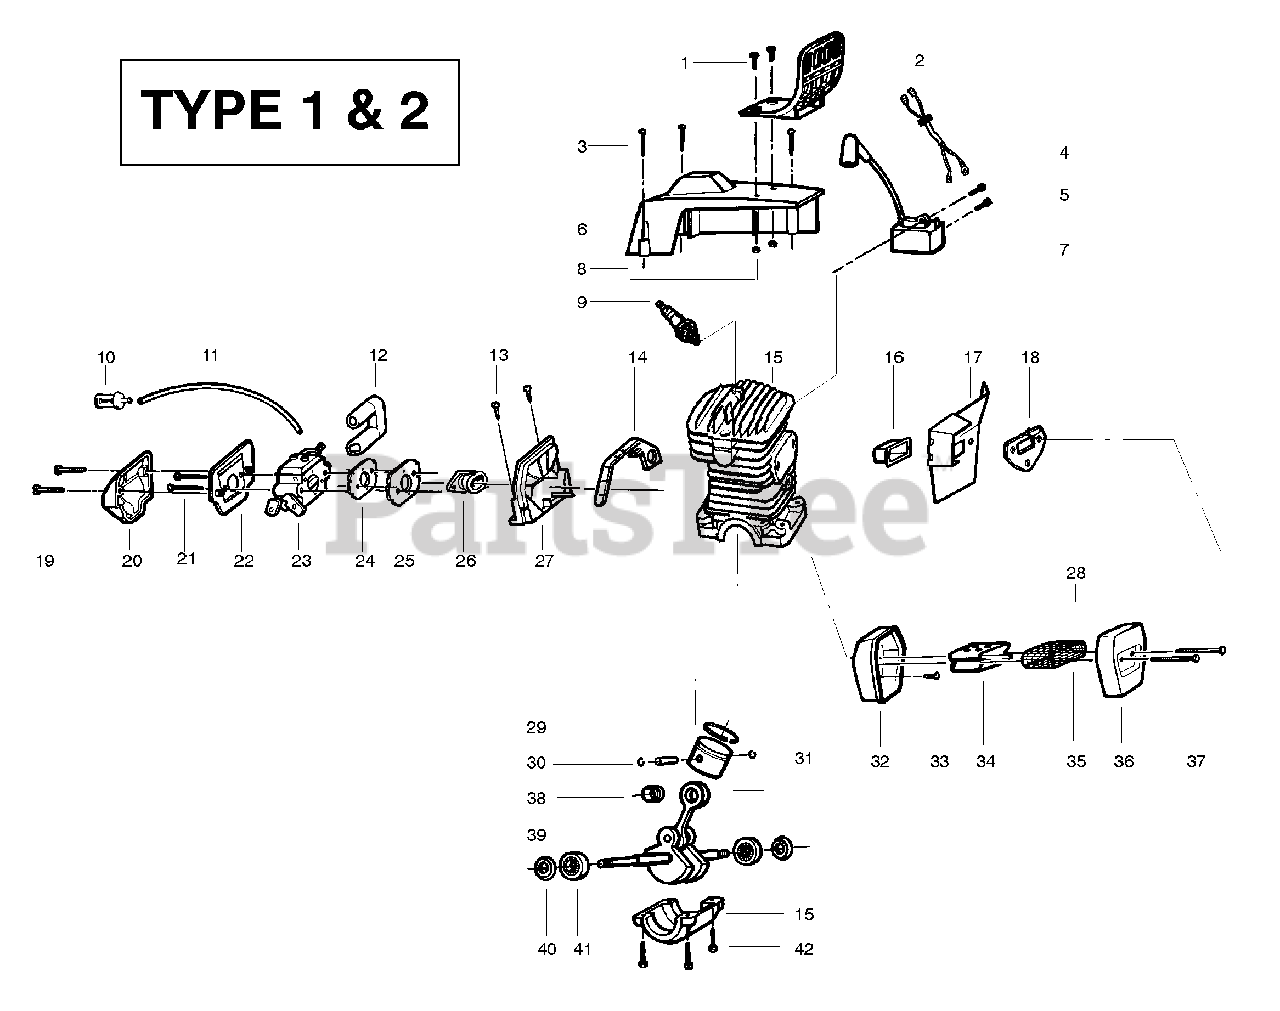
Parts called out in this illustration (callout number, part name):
1	Screw
2	Handguard
4	Switch Wire Ass'y.
6	Cylinder Shield Kit
7	Ignition Module
8	Nut
9	Spark Plug
10	Fuel Pick-up Assy.
11	Kit - Line Carb / Purge
12	Carb. Grommet
14	Super Clean Seal
15	C'case&Cylinder Assy
16	Heat Insulator
17	Muffler Plate
18	Muffler Gasket
20	Air Filter
22	Air Filter
23	Carburetor
24	Carburetor Gasket
25	Carburetor Plate
26	Intake Boot
27	Carb. Adaptor
28	Muffler Kit
29	Piston Ring
30	Piston Pin Retainer
31	Piston Kit
32	Muffler Body
34	Diffuser
35	Spark Screen
36	Muffler Cover
37	Muffler Bolt
38	Piston Pin Bearing
39	C'shaft & Rod Ass'y.
40	C'shaft Seal
41	C'shaft Bearing
